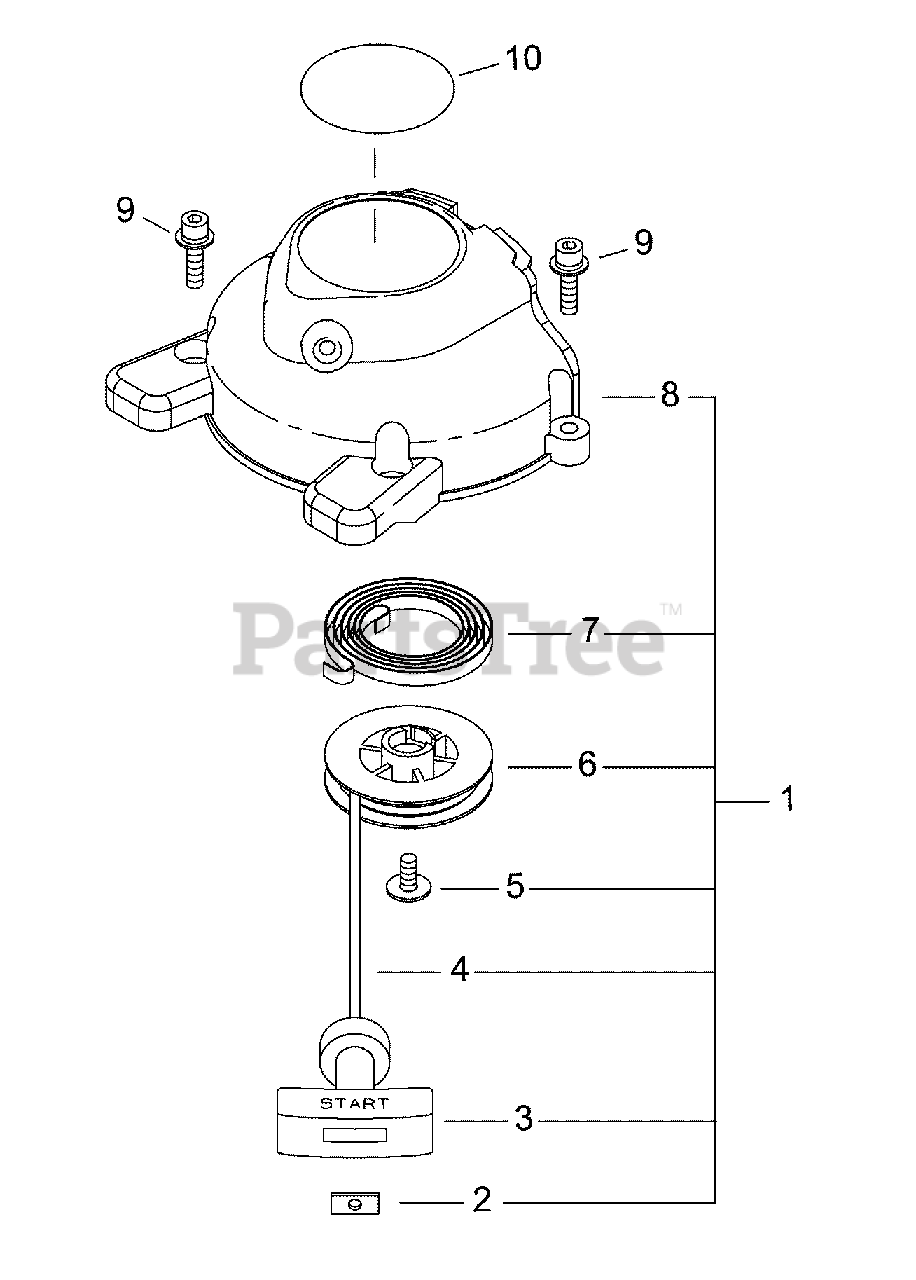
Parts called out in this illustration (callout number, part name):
1	STARTER ASSY
2	RETAINER, ROPE
3	GRIP, STARTER
4	ROPE, STARTER
5	SCREW - 5
6	REEL, ROPE
7	SPRING, REWIND
8	CASE, STARTER
9	SCREW - 5X20
10	LABEL - E4
